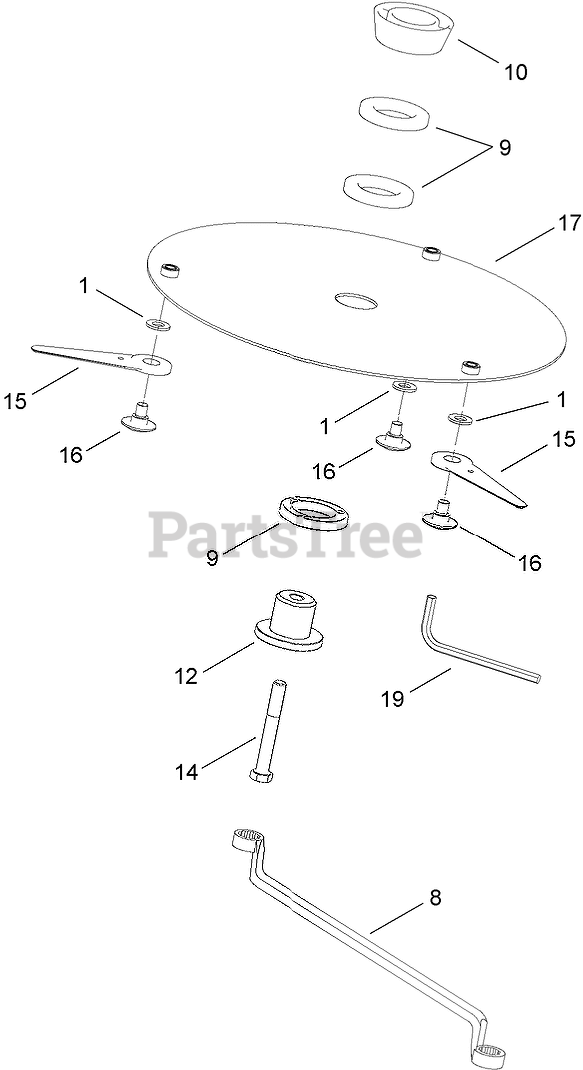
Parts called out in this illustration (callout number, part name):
1	WASHER-PLAIN
8	SPANNER
9	SPACER-BLADE, ALUMINIUM
10	SPACER-DISTANCE
12	RETAINER-BLADE
14	SCREW-SET
15	BLADE PLASTIC
16	BOLT SHOULDER SPECIAL
17	18 INCH TRIM DISC
19	WRENCH-HEX
